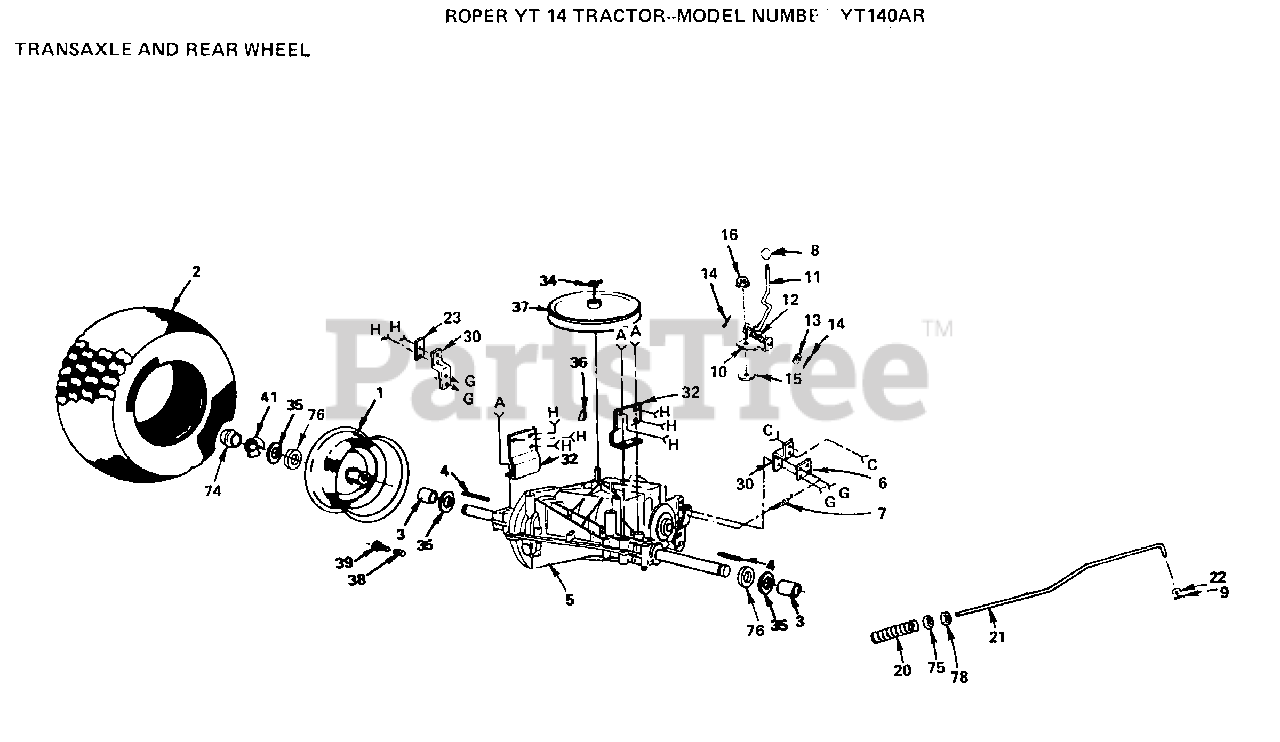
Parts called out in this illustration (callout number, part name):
3	"SPACER, SPLIT LT"
6	BRACKET-SPRING LT
7	SPRING-EXT LT
8	KNOB T (1/2-HOLE)
9	COTTER PIN
10	PLATE SHIFT LT
12	SPRING LT
13	WASHER
14	PIN COTTER 1/8
15	WASH-SHFT PLT LT
20	SPRING ROD LT
22	WASHER
23	PLATE-STRAP LT
30	"STRAP, TORQUE LT"
38	VALVE CAP
39	VALVE STEM LT
41	E-RING LT
74	HUB CAP
75	LOCKNUT
78	NUT
